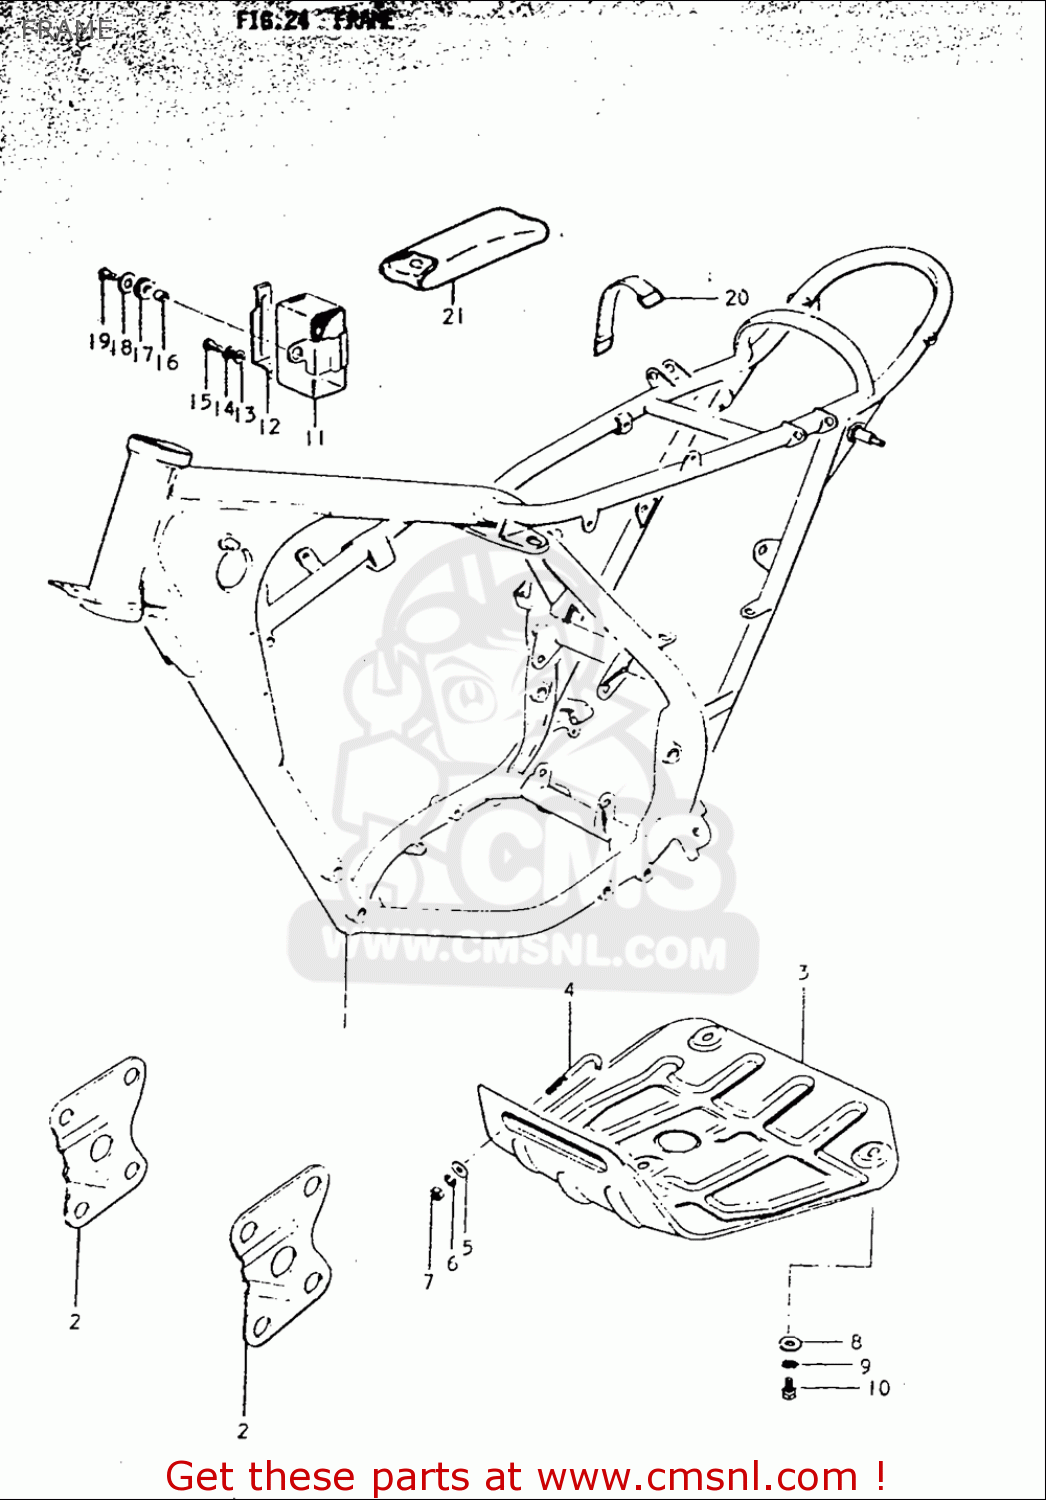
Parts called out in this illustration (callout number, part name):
5	WASHER
6	WASHER,LOCK
7	NUT
8	WASHER
9	WASHER,LOCK
10	BOLT
13	WASHER
14	WASHER,LOCK
15	SCREW(6X10)
16	SPACER,6.5X9X7
17	CUSHION
18	WASHER(6.5X20X1.2)
19	SCREW
20	BAND
